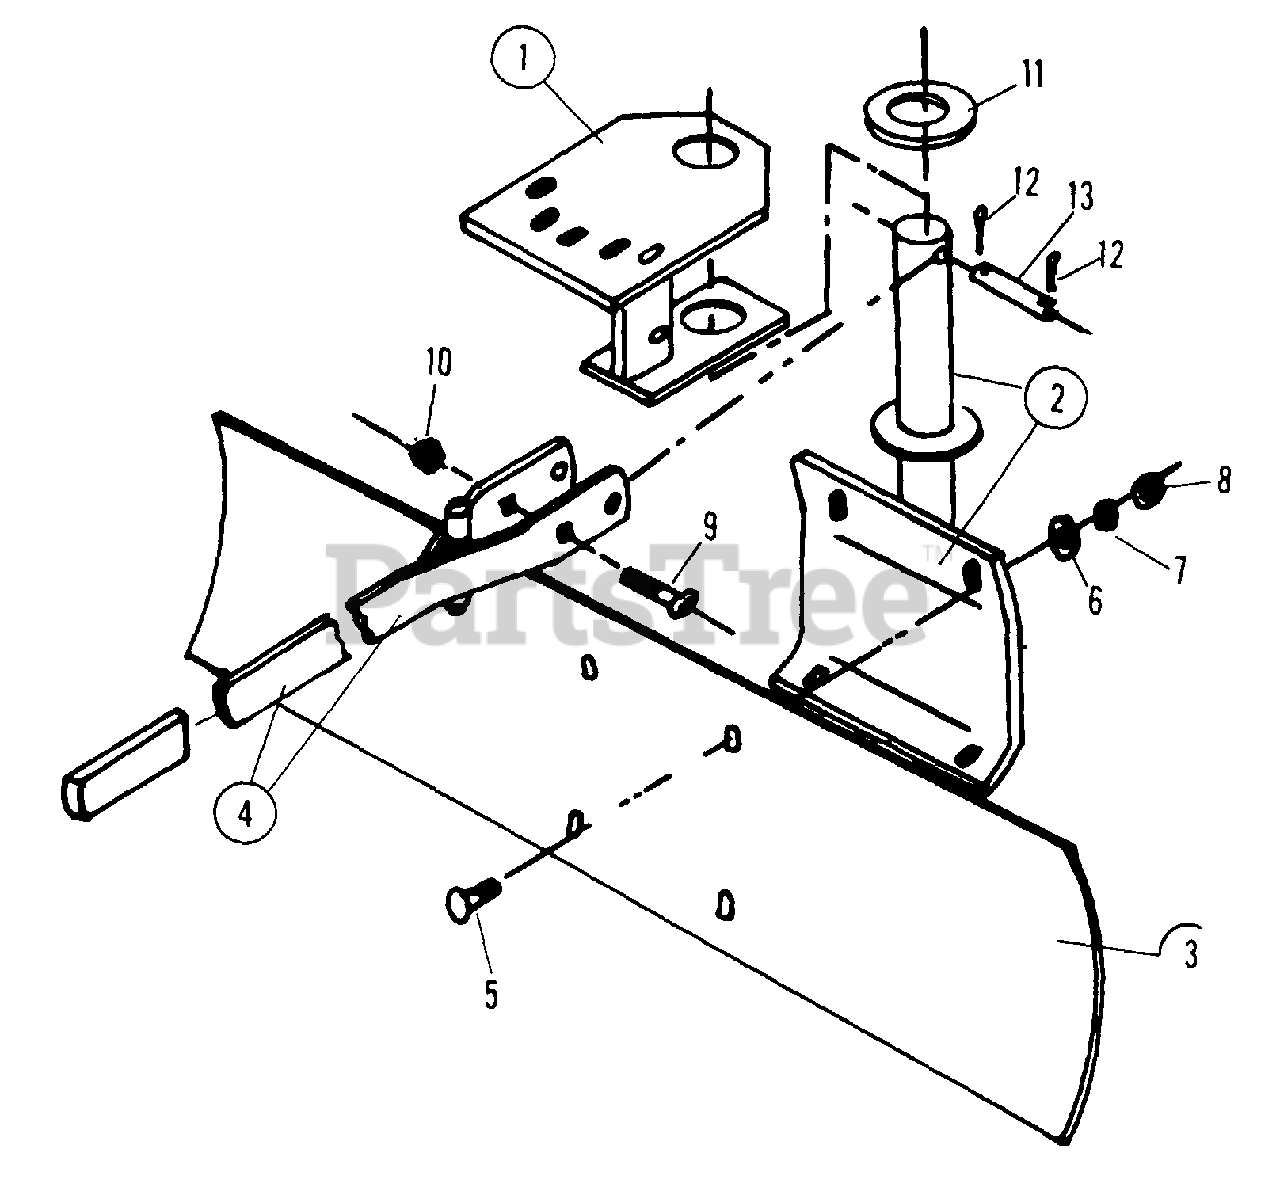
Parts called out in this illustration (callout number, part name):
1	BRACKET, PIVOT
2	MOUNT, BLADE
3	BLADE, 42"
4	BAR, ANGLING
5	BOLT, 3/8 x 1" CARRIAGE
6	WASHER, 3/8 PLAIN
7	LOCKWASHER, 3/8"
8	NUT, 3/8 HEX
9	BOLT, 3/8 x 2-3/4 CARRIAGE
10	LOCKNUT, 3/8 HEX
11	WASHER, 1-1/4"
12	COTTER-PIN, 1/8" D x 1"
13	SHEAR-PIN, 7/16"
